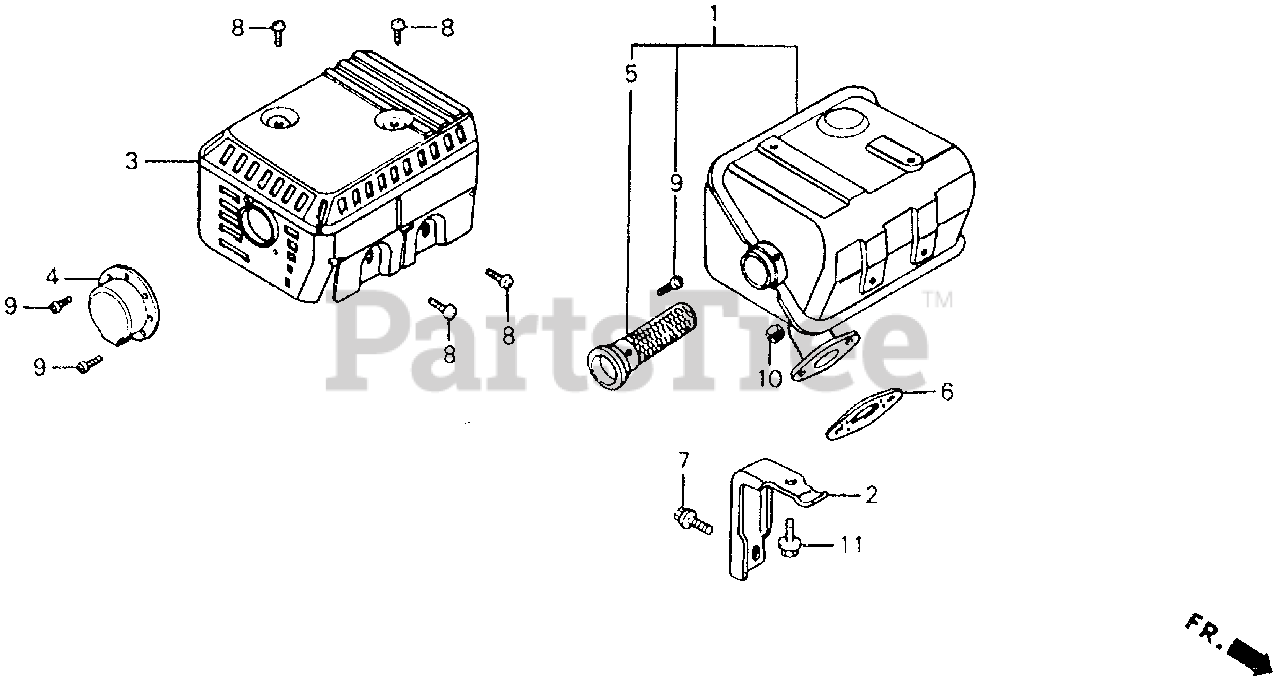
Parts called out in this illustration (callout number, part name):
1	MUFFLER (SILENT)
2	STAY, MUFFLER
3	PROTECTOR, MUFFLER (SILENT)
3	PROTECTOR, MUFFLER
4	CAP, MUFFLER
5	ARRESTER, SPARK (SILENT)
6	GASKET, MUFFLER
7	BOLT, FLANGE (6X13)
8	SCREW, TAPPING (5X8)
9	SCREW, TAPPING (4X6)
10	NUT, HEX. (8MM)
11	BOLT, FLANGE (6X12)
